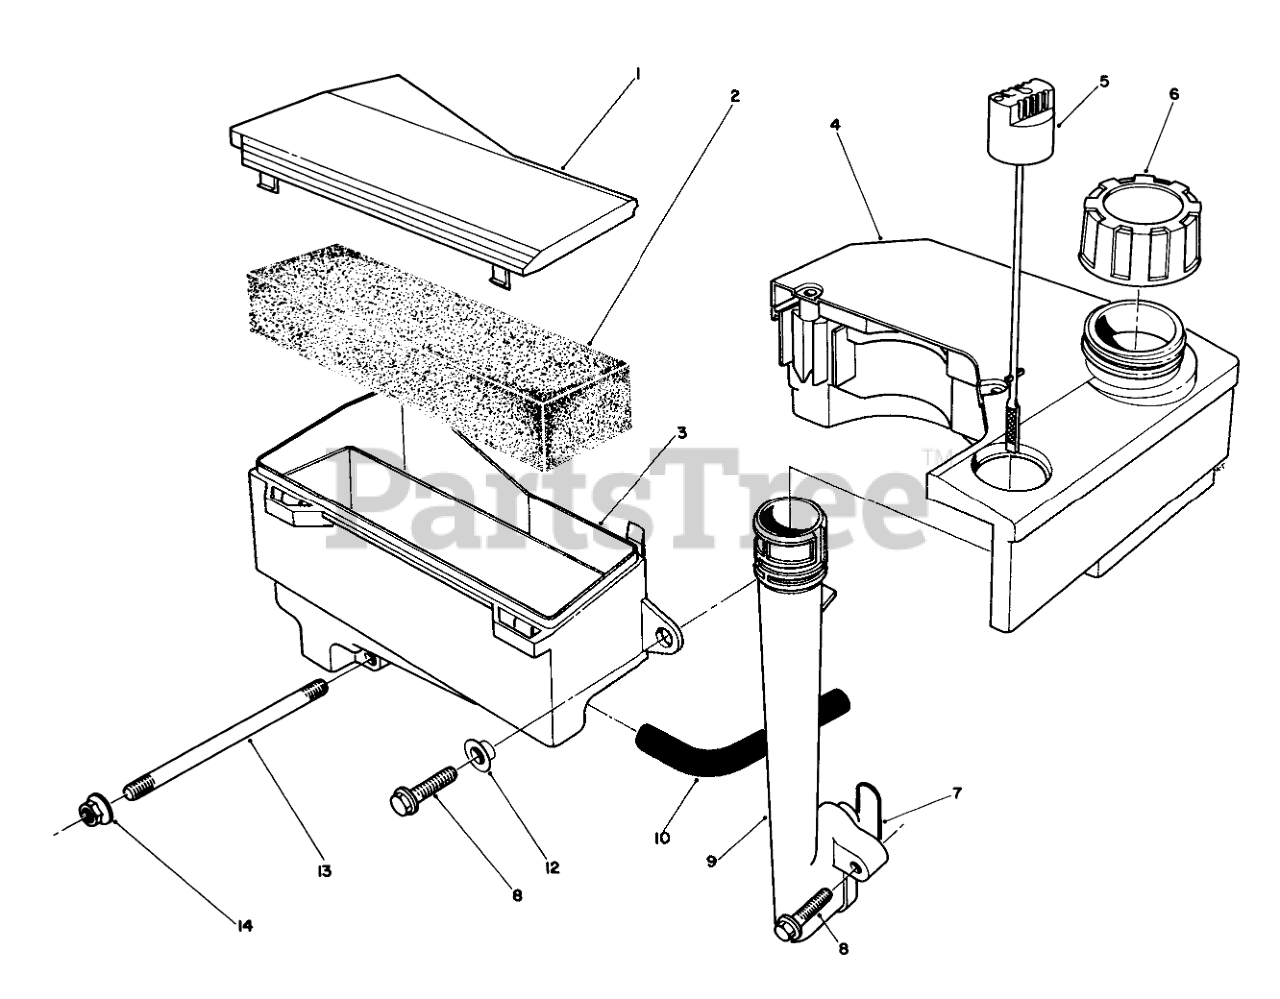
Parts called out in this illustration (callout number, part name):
1	AIR CLEANER CAP
3	Body-Air Cleaner
4	TANK ASM
5	Dipstick
6	GAS CAP ASM
7	0-Ring-Oil Tube
12	SPACER
13	Stud-Carburetor
